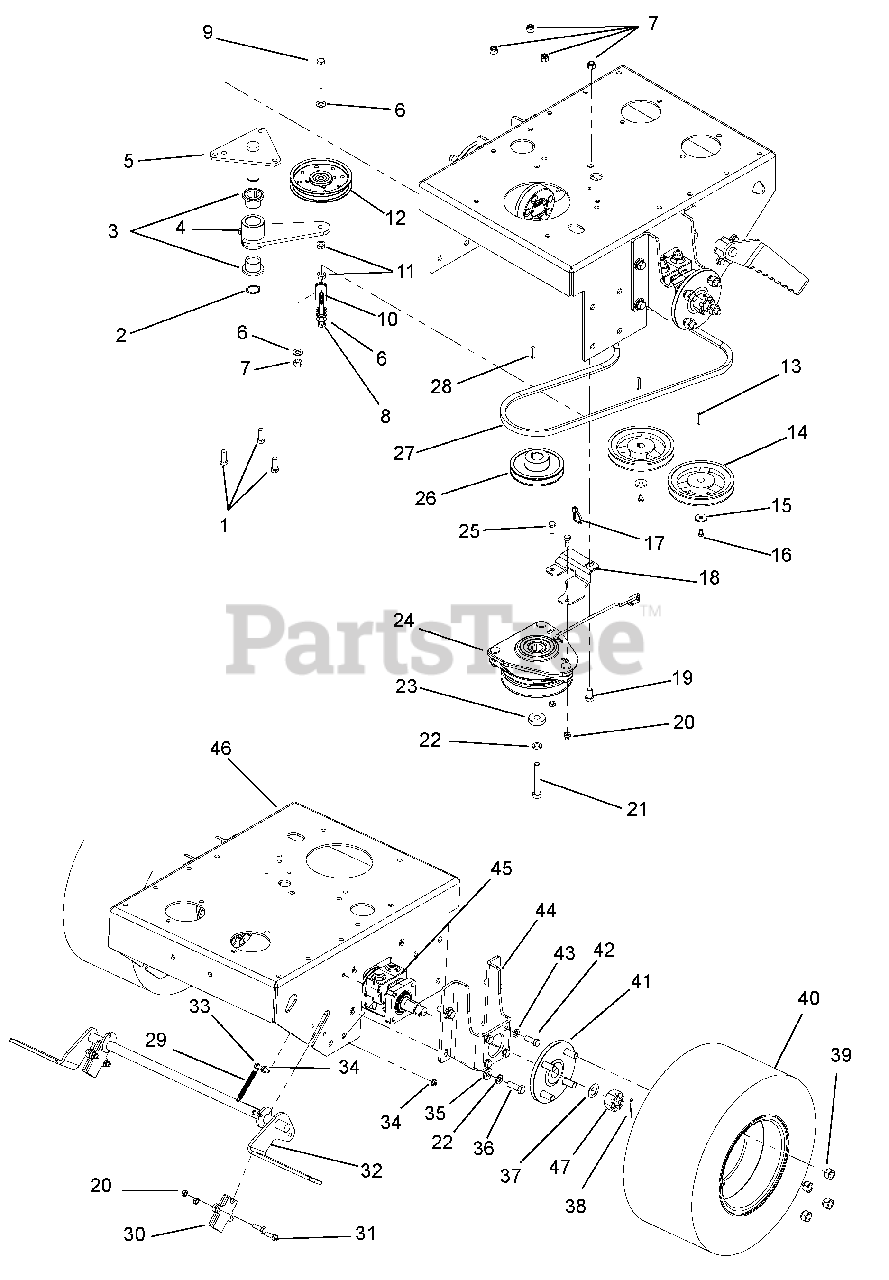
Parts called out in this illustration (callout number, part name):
1	BOLT, 3/8-16 X 1.00 HEX 5 Y
2	SNAP RING, 1.00 X .042 EXT
3	BRG, FLG 1.00 X 1.25 X 1.00
4	WLDT, IDLER ARM
5	WLDT, IDLER PIVOT MOUNT
6	WASHER, .406 X .813 X .065 FLAT Y
7	LOCKNUT, 3/8-16 NYLOC Y
8	BOLT, 3/8-16 X 3.00 HEX 8 Y
9	BOLT, 3/8-16 X 2.50 HEX 5 Y
10	SPRING, EXT .900X.135X4.50 Y
11	LOCKNUT, 3/8-16 WHIZ Y
12	PULLEY, FLAT 4.50 X .375 W/BRG
13	KEY, M5 X M5 X M30 RD
14	ASSY, PUMP PULLEY W/SET SCREW
15	WASHER, .250 WIDE HEAVY FLAT Y
16	BOLT, M6X1.00X10 HEX 8.8 Y
17	CABLE TIE, .15 X 8.50
18	PLATE, CLUTCH DOG
19	BOLT, 7/16-14 X .750 HEX 5 Y
20	LOCKNUT, 5/16-18 NYLOC Y
21	BOLT, 7/16-20 X 3.00 HEX 5 Y
22	WASHER, .438 MED SPRG LOCK Y
23	SPACER, .468 X 1.38 X .375 Y
24	CLUTCH ASSY, OGURA
25	BOLT, 5/16-18 X .750 HEX 5 Y
26	PULLEY, V-BELT 4.45X1.00 W/KEY
27	BELT, HA 55.1 EL AMD OHR
28	KEY, .250 X .250 X .995 TPR
29	SPRING, EXT .375 X .055 X 2.25 Y
30	SHOE, BRAKE SYSTEM FLOAT WALK
31	BOLT, 5/16-18 X 1.00 HEX 5 Y
32	WLDT, BRAKE SYS 36" FLWLK
33	BOLT, 1/4-20 X 1.25 HEX 5 Y
34	LOCKNUT, 1/4-20 WHIZ Y
35	WASHER, .468X1.00X.125 FLAT Y
36	BOLT, 7/16-14 X 1.25 HEX 5 Y
37	BUSHING, MACH .750X1.25X.048 Y
38	PIN, COT .125 X 1.50 EXTP Y
39	NUT, 1/2-20 LUG C
40	ASSY, WHEEL & TIRE - 16X6.5-8
41	ASSY, WHEEL HUB
42	BOLT, 3/8-16 X 1 GR8 BLACK
43	WASHER, .375 MED SPRG LOCK Y
44	BRKT, MOTOR MOUNT FLWLK
45	MOTOR, HYDRAULIC WHEEL
46	WLDT, ENGINE BED 36 GRAVELY
47	NUT, .75 UNF2B HEX SLOT JDS14
